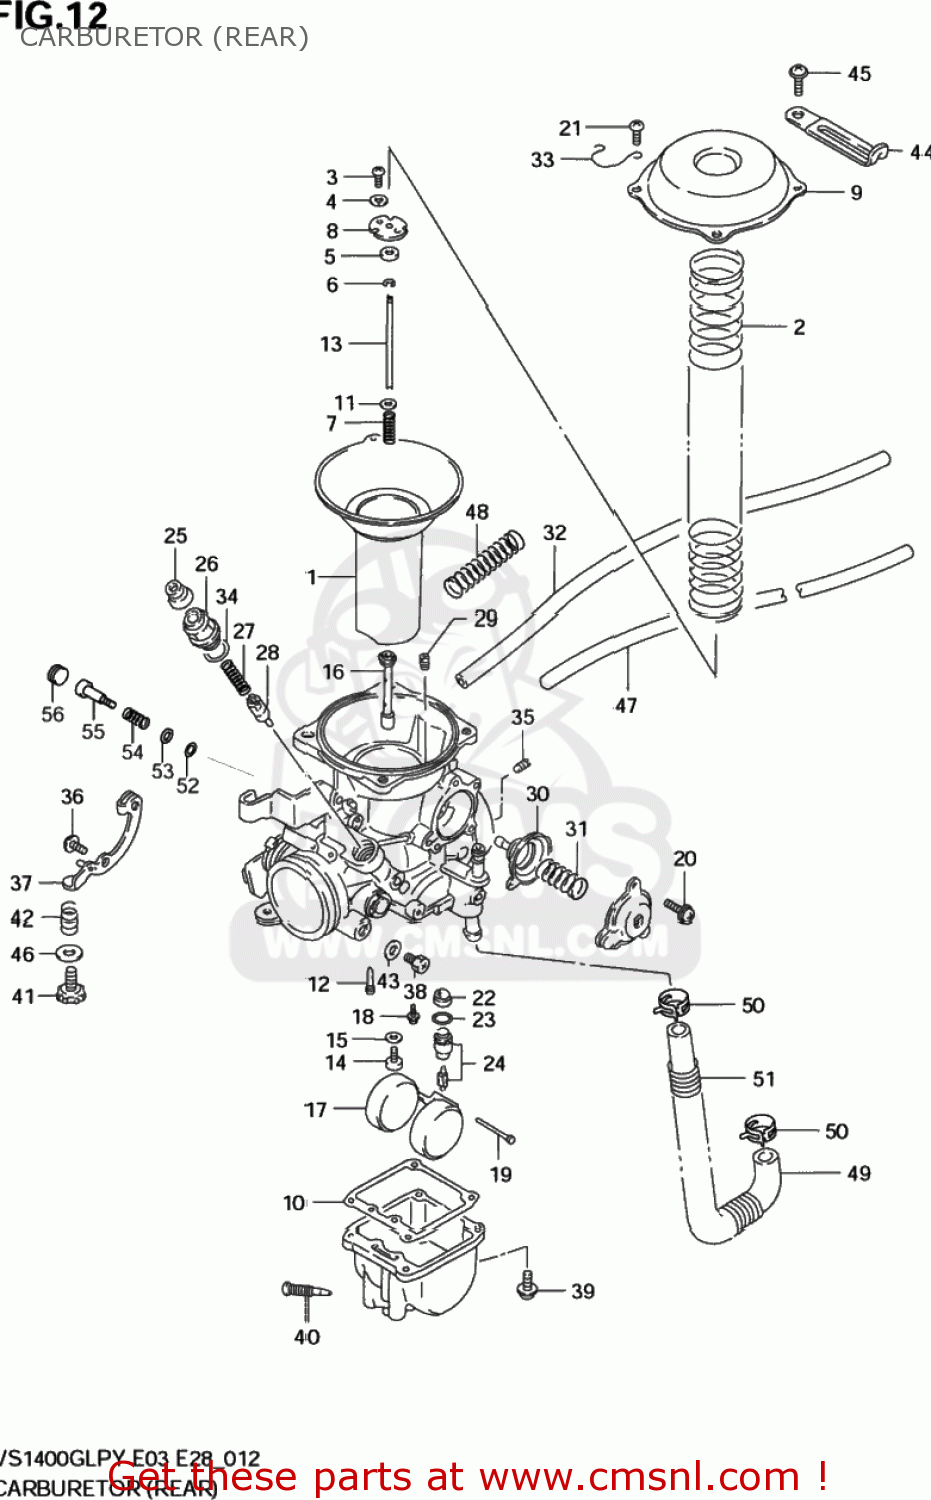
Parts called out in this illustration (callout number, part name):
1	DIAPHRAGM ASSY
2	SPRING,DIAPHRAGM
3	SCREW
4	WASHER,LOCK
5	RING
6	CLIP
7	SPRING
8	PLATE
9	COVER
10	GASKET,FLOAT CHAMBER (NAS)
11	WASHER
12	JET,PILOT
13	NEEDLE,JET
14	JET,MAIN(140)
15	WASHER
16	JET,NEEDLE
17	FLOAT
18	SCREW
19	PIN,FLOAT
20	SCREW
21	SCREW
22	FILTER
23	O-RING,NEEDLE VALVE
24	VALVE ASSY,NEEDLE
25	CAP
26	HOLDER,GUIDE
27	SPRING
28	PLUNGER,STARTER
29	JET,AIR(1.9)
30	DIAPHRAGM ASSY
31	SPRING
32	HOSE ASSEMBLY
33	CLIP
34	O RING
35	JET
36	SCREW
37	LEVER ASSY
38	SCREW
39	SCREW
40	PLUG,DRAIN
41	ADJUSTER
42	SPRING
43	WASHER
44	CLAMP(L:80 T:1.0)
45	SCREW
46	WASHER
47	(CA) HOSE SET,FUEL
48	SPRING
49	HOSE,FUEL PUMP & CARBURETOR
50	CLIP
51	SPRING
52	O RING,PILOT AIR SCREW
53	WASHER
54	SPRING
55	SCREW,PILOT
56	PLUG
